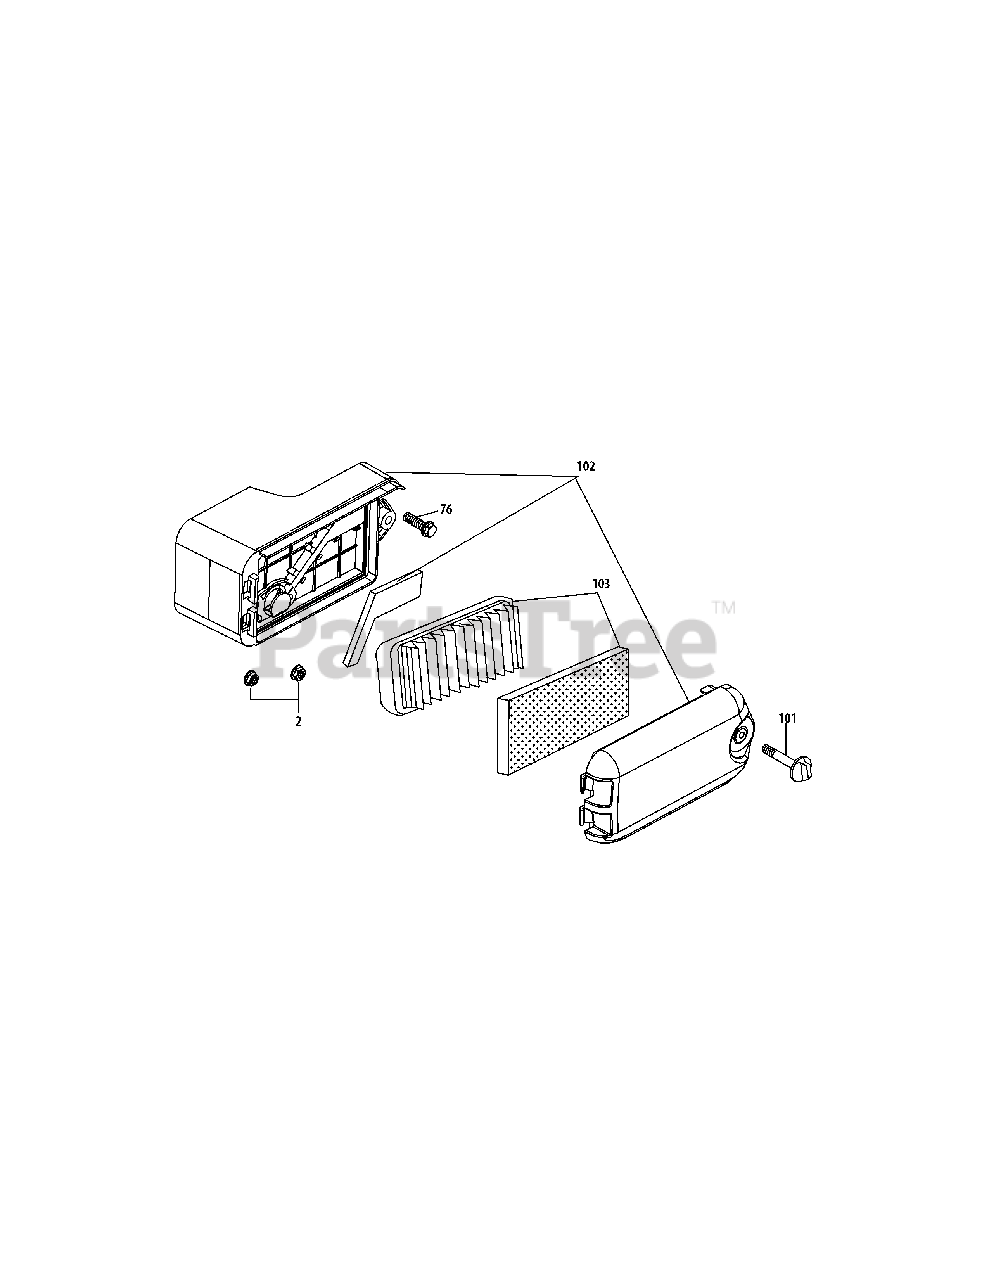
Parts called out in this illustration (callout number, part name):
2	Nut M6
76	Bolt M6×35
101	Air Filter Cover Thumb Screw
102	Air Filter Base
103	Air Filter Element,Sponge
